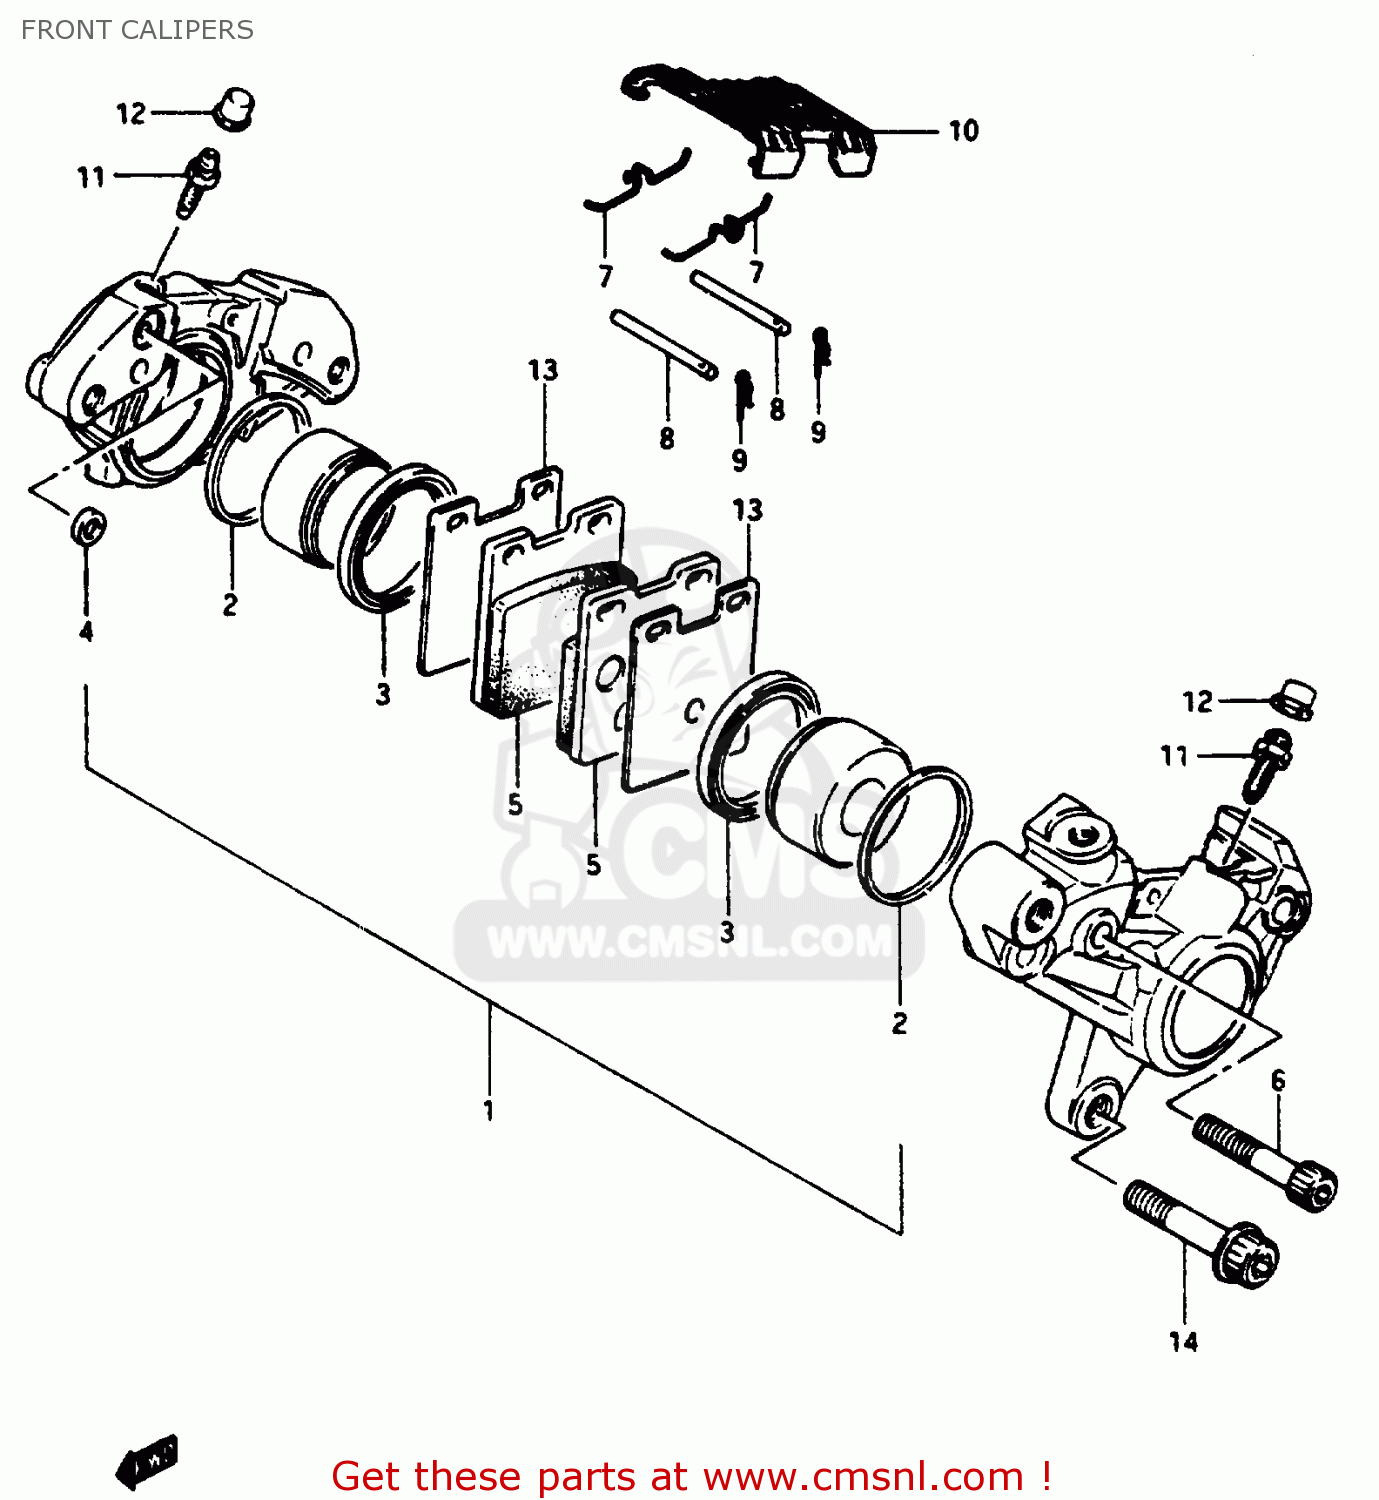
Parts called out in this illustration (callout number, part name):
1	PISTON SET
2	SEAL,PISTON
3	BOOT,PISTON
4	SEAL,JOINT
5	PAD,BRAKE
6	BOLT,CALIPER
7	SPRING
8	PIN,PAD
9	CLIP,PAD PIN
10	COVER,CALIPER
11	BLEEDER
12	CAP,BREATHER
13	SHIM,PAD
14	BOLT
